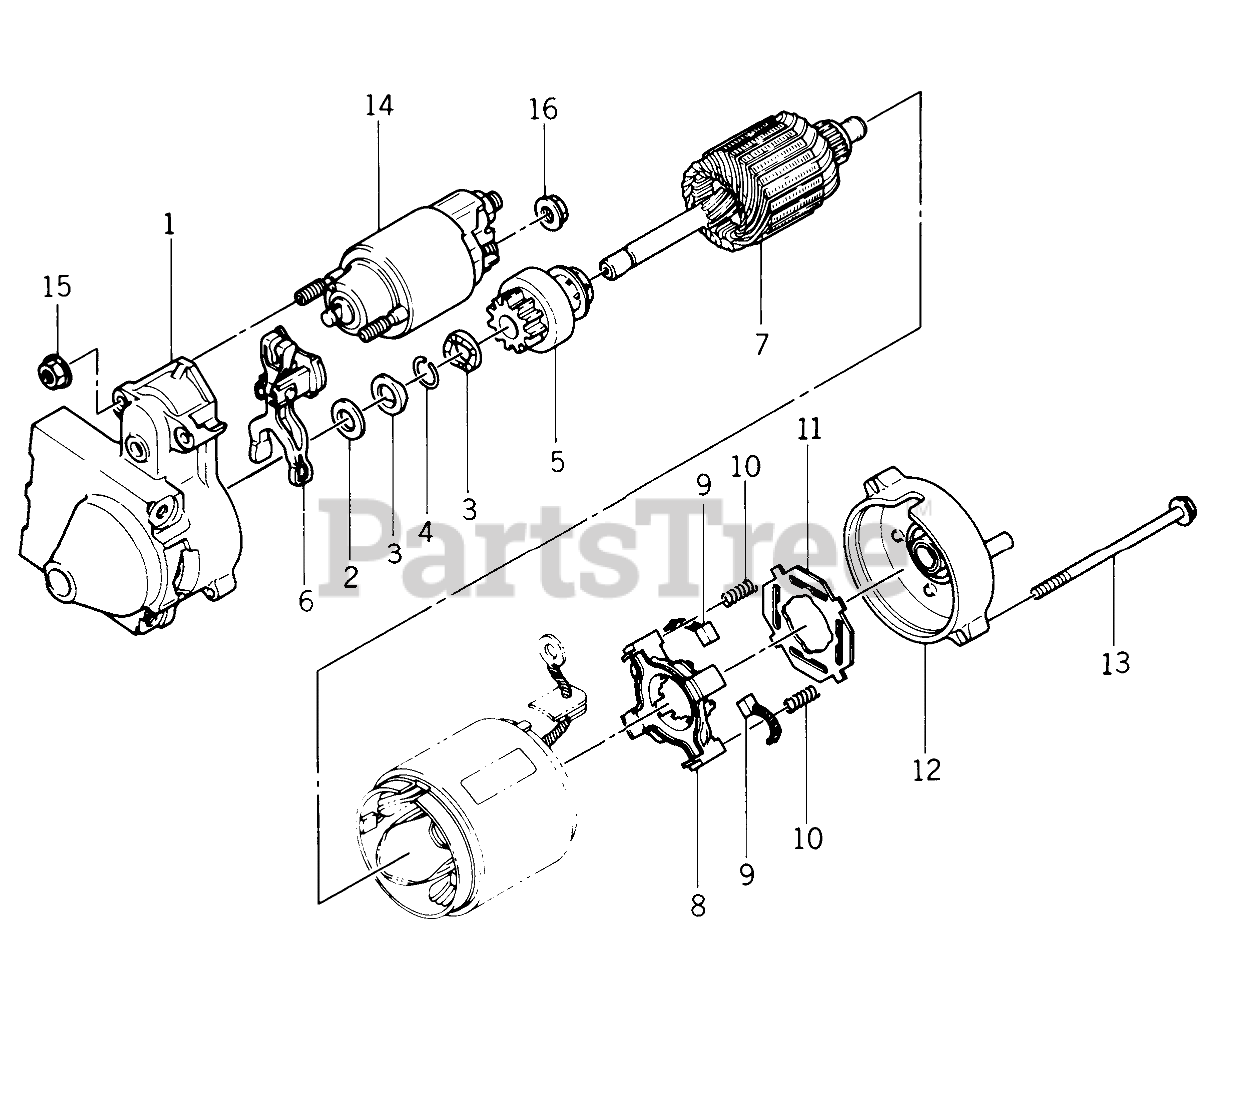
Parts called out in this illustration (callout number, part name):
1	COVER ASSY
2	WASHER
3	STOPPER
4	RING-SNAP
5	CLUTCH ASSY
6	LEVER-SHIFT
7	ARMATURE
8	HOLDER-BRUSH
9	BRUSH
10	SPRING-BRUSH
11	INSULATOR
12	COVER ASSY
14	SWITCH ASSY
